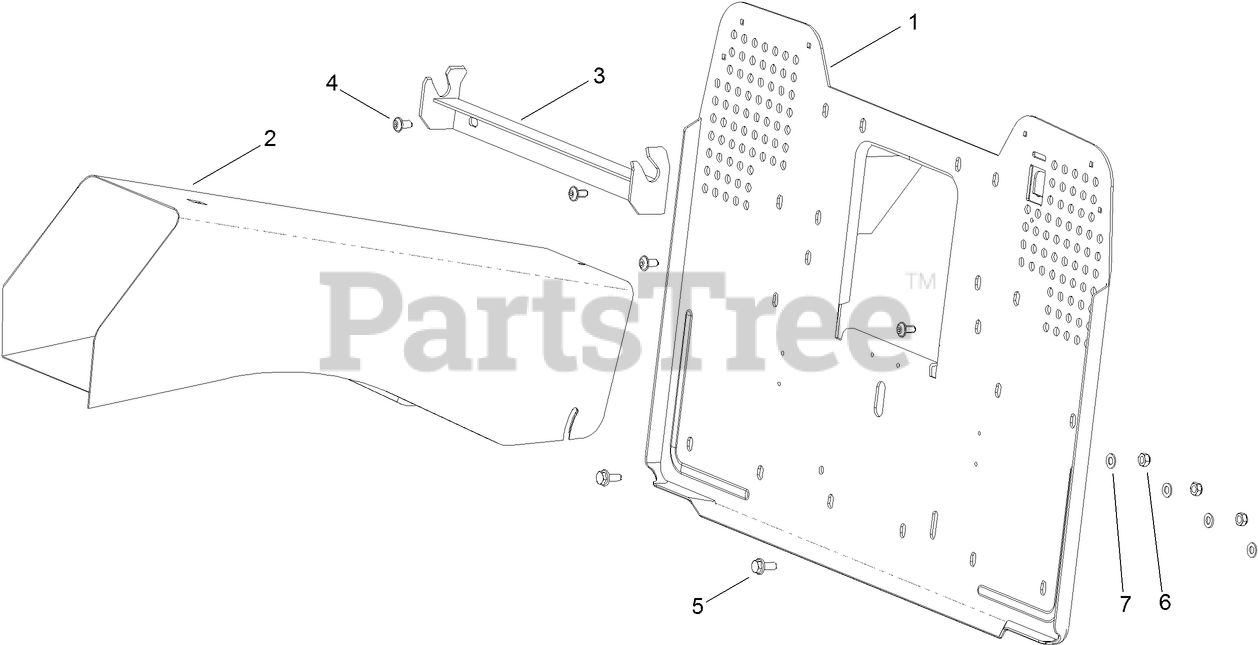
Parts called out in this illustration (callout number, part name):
1	COLLECTOR PLATE ASM
2	TUNNEL
3	SUPPORT-COLLECTOR
4	BOLT-CARRIAGE
6	NUT-LOCK, NI
7	WASHER-PLAIN
